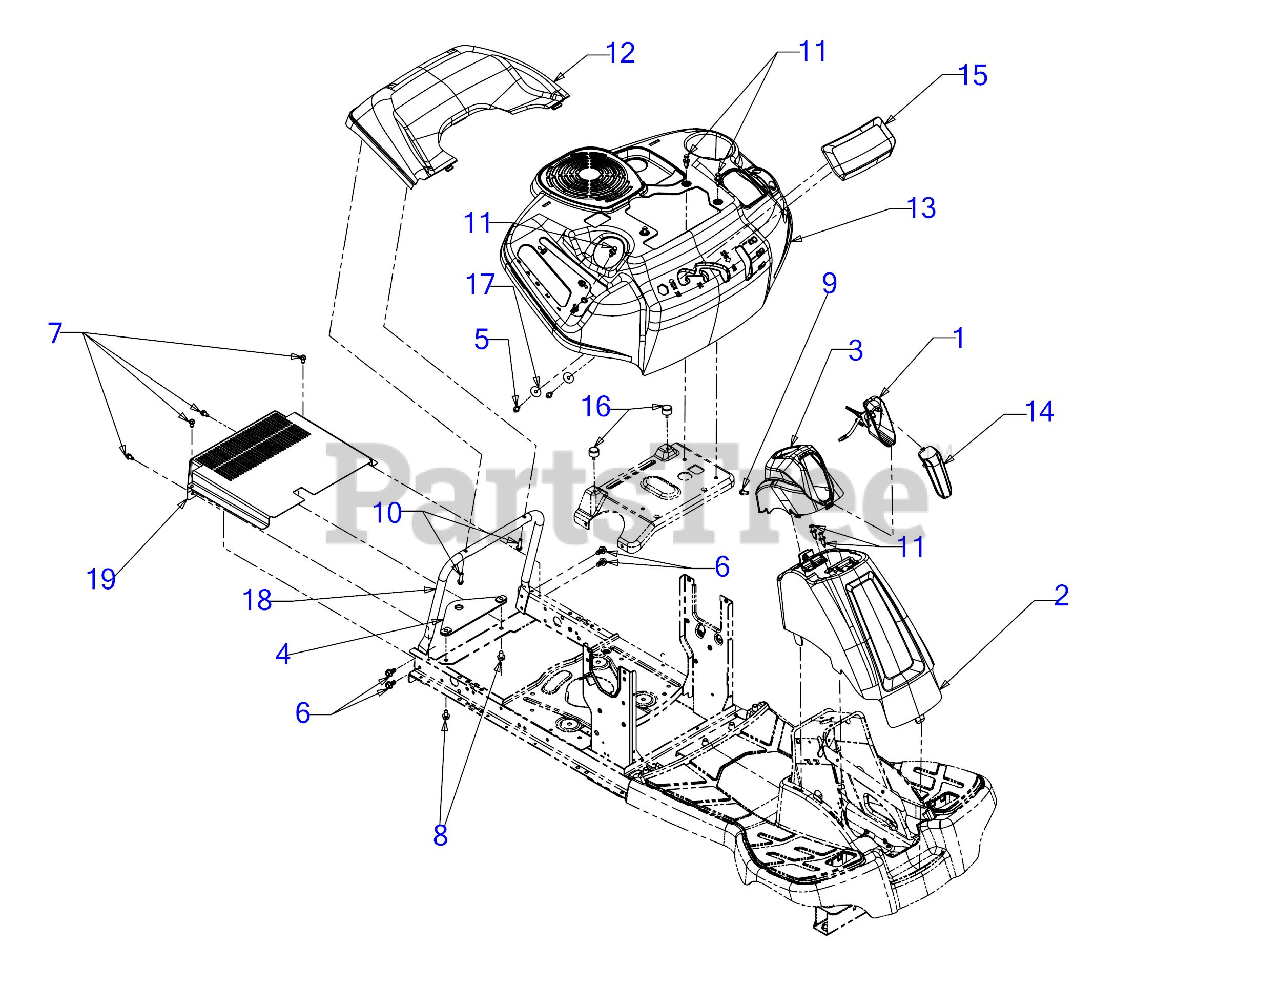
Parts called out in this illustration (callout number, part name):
1	HEADLIGHT HARNESS ASSEMBLY
2	COLUMN COVER ASSEMBLY (CUB)
3	COLUMN CAP (CUB YELLOW)
5	HEX SCREW 1/4-15 x .50
6	SCREW 5/16-18 x .750
7	SCREW 1/4-20 X.500
8	SCREW 5/16-18 x .625
9	SCREW 1/4-20X.75
10	SCREW 1/4-15 x 1.00
11	PLASTIC RIVET
14	LED HEADLIGHT LENS
15	FENDER COVER
16	BUMPER .62 DIA x .50
17	FLAT WASHER
19	HEAT SHIELD
